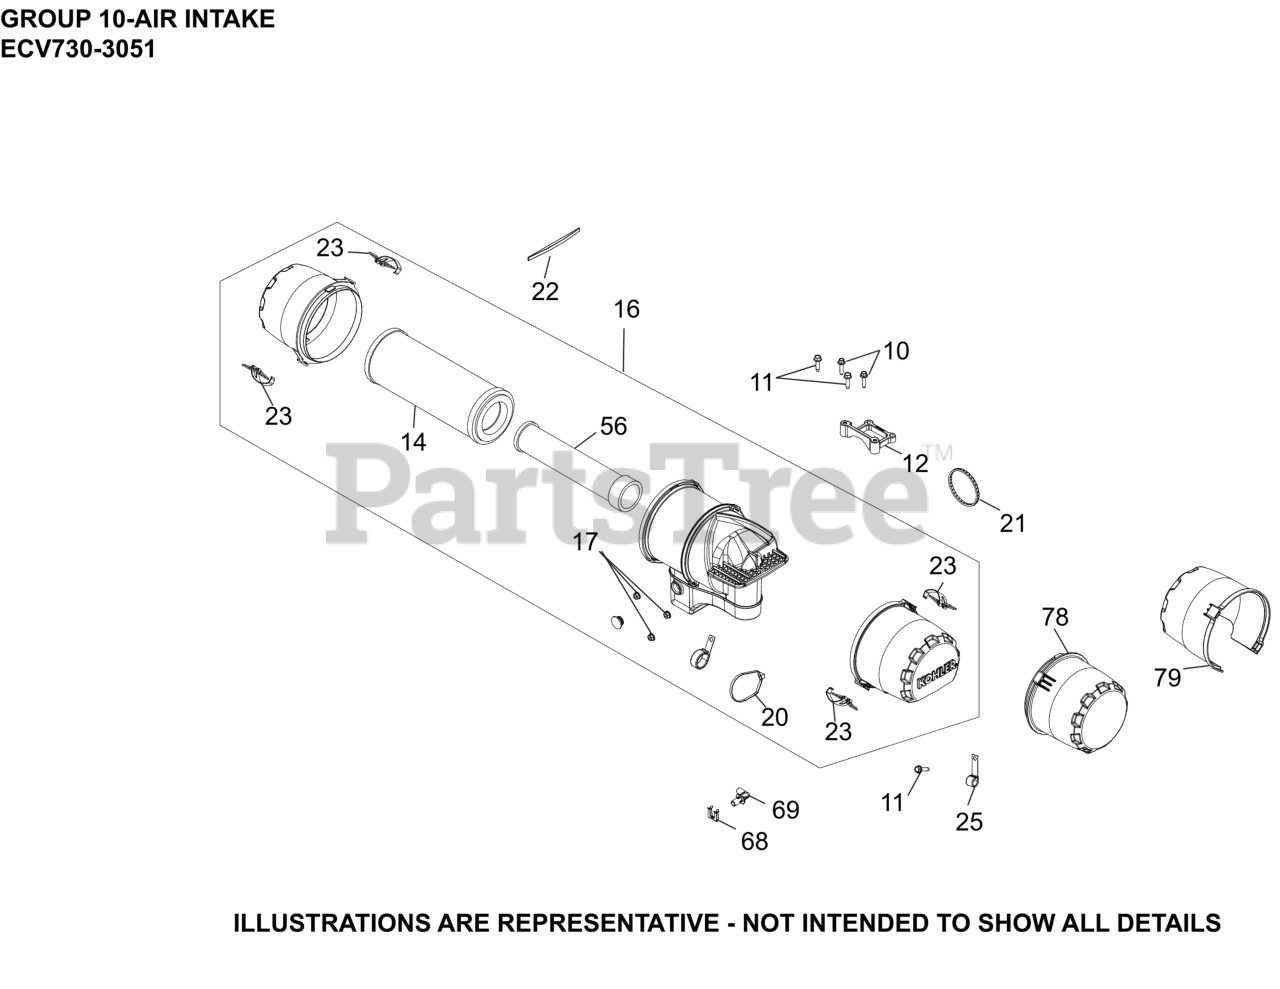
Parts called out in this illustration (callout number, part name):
10	SCREW, FLG M6X1.0X25
11	SCREW, THREAD FORMING
12	AIR CLEANER BRACKET
14	ELEMENT, AIR FILTER - PRIMARY
16	KIT, AIR CLEANER
17	NUT, FLG M6X1.0
21	O-RING (HDAC SEAL-EFI)
22	DAMPER, FOAM INSERT
23	CLIP ASSEMBLY
25	CLIP, CABLE
56	ELEMENT, AIR FILTER - SAFETY
68	CLIP, BAFFLE MOUNTING
69	FITTING, CONNECTOR EVAP
78	COVER, AIR FILTER
79	COVER, RAIN CAP
